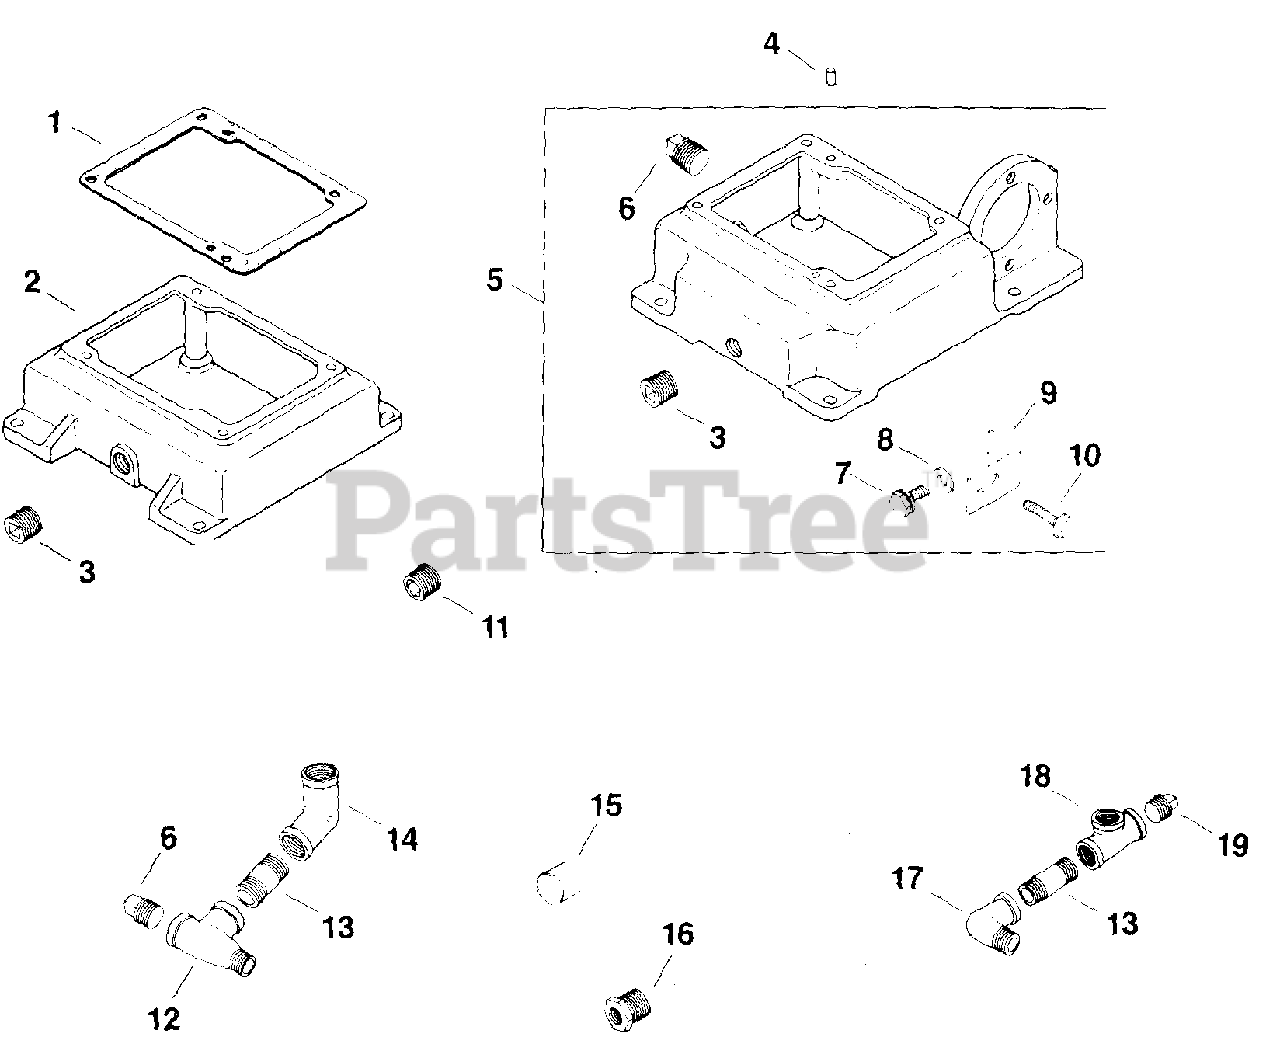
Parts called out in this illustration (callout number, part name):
1	GASKET - DISCONTINUED
3	PLUG, PIPE 3/4 NPTF SQ CTSK USE 25 139 66-S
5	KIT, OIL PAN - DISCONTINUED
6	PLUG,PIPE SQ HD 3/4" USE 25 139 56-S
6	PLUG,PIPE 1/2 NPTF SQUARE HD USE 25 139 61-S
9	BRACKET - DISCONTINUED
10	SCREW, WSH HD TAP 1/4-20X3/4" USE 25 086 100-S
